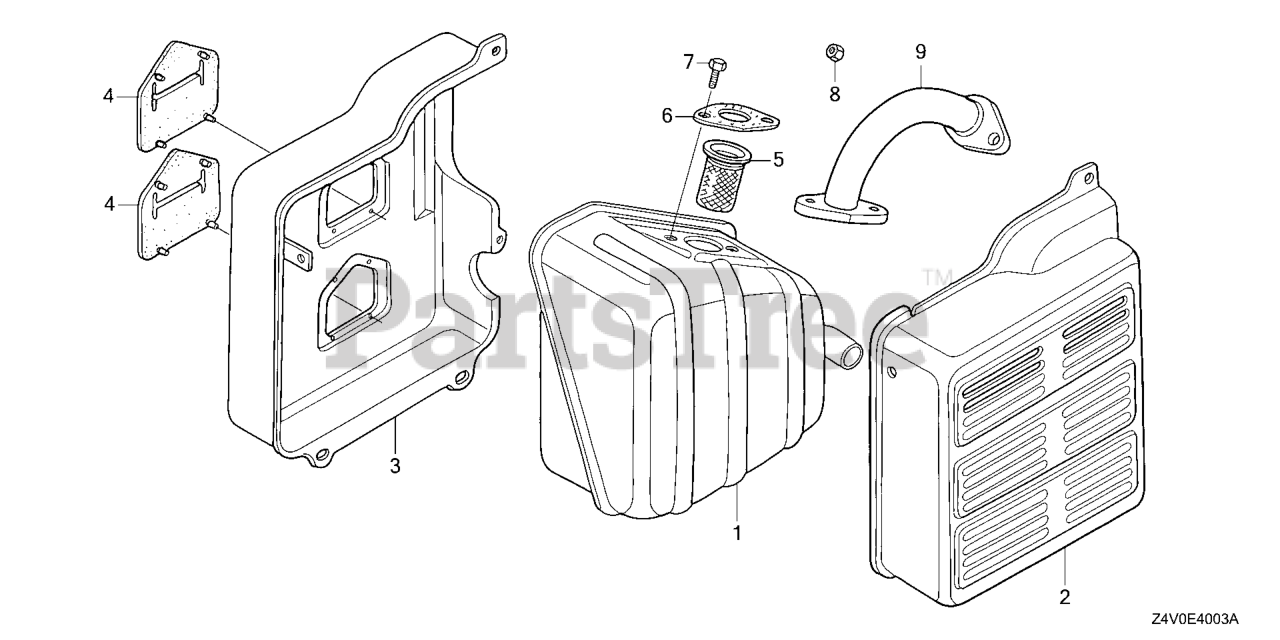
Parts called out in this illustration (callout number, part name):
1	MUFFLER
2	PROTECTOR, MUFFLER (OUTER)
3	PROTECTOR, MUFFLER (INNER) (DENYO)
4	SEAL, MUFFLER PROTECTOR
5	ARRESTER, SPARK
6	GASKET, MUFFLER
7	BOLT, HEX. (8X20)
8	NUT, HEX. (8MM)
